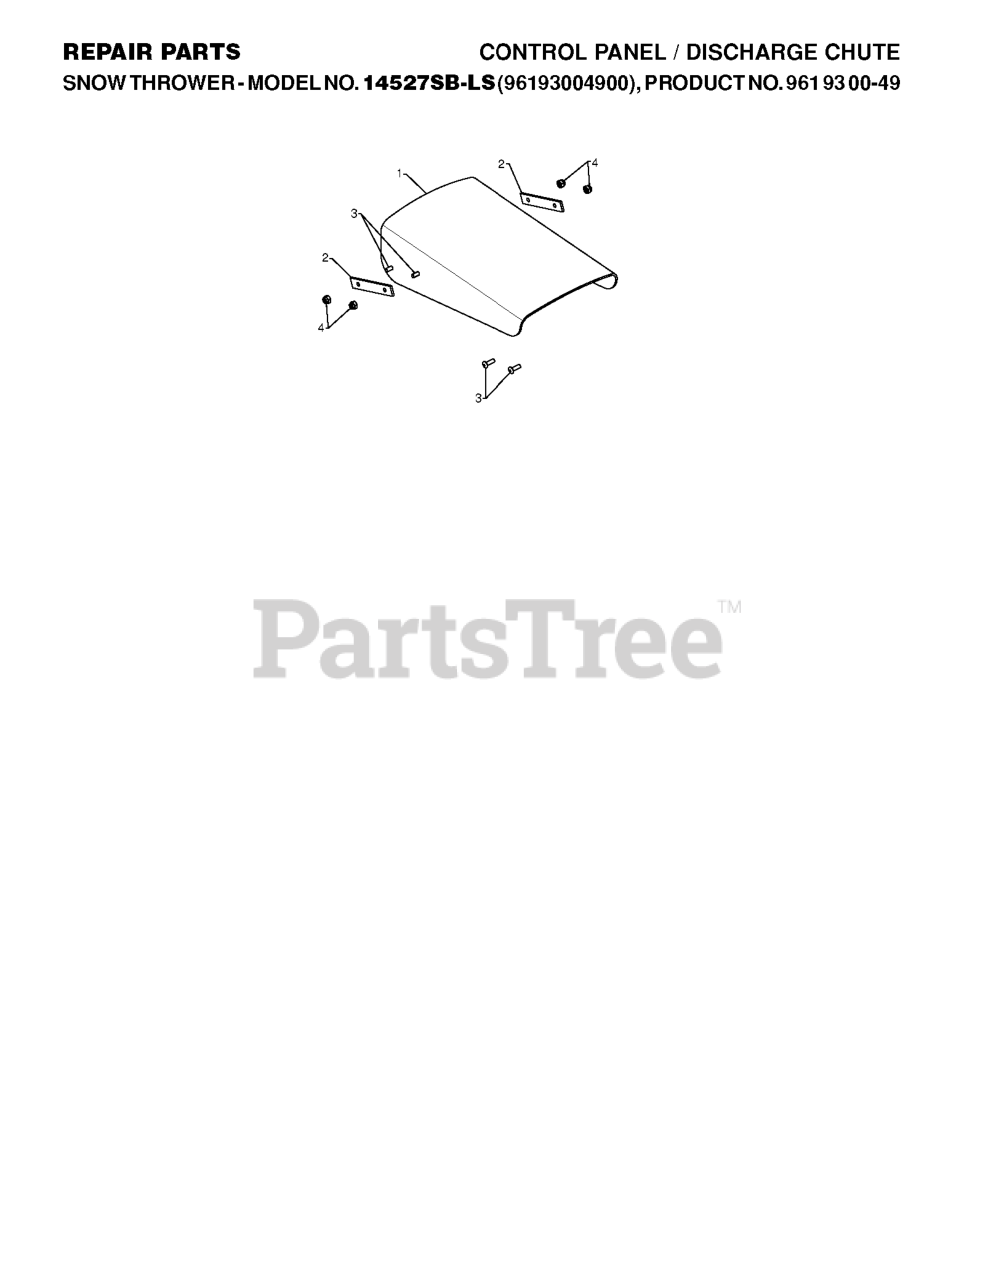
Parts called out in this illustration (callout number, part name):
1	SHIELD.DEFLECTOR.BLACK.SNOW
2	DEFLECTOR SHIELD STRAP
3	SCREW.#8.MACH
4	NUT.HEX.#8
